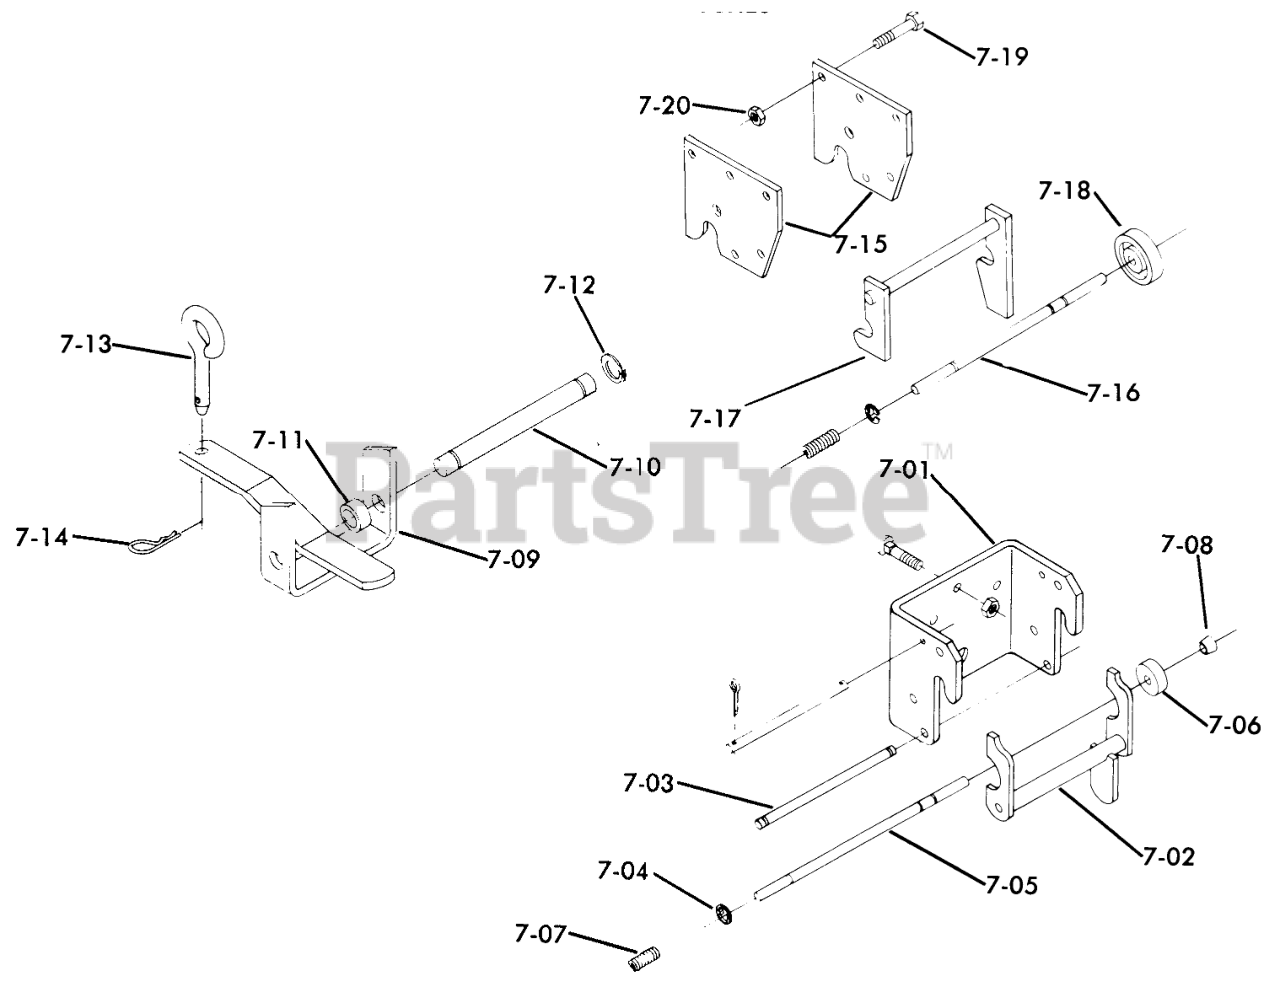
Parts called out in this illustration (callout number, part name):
7-01	Front Hitch
7-02	Assy-Latch
7-03	ROD-LATCH PIVOT
7-04	Lock Rod
7-05	ROD-LOCK
7-07	SPRING
7-08	CAP-ROD, PLUNGER
7-09	Hitch
7-10	PIN-STATIONARY HITCH
7-11	Spacer
7-12	E-RING
7-13	Pin-Tool
7-14	Hairpin Cotter
7-15	Hitch Plate
7-17	ASSY MID HITCH LA R
7-19	BOLT
7-20	Nut
